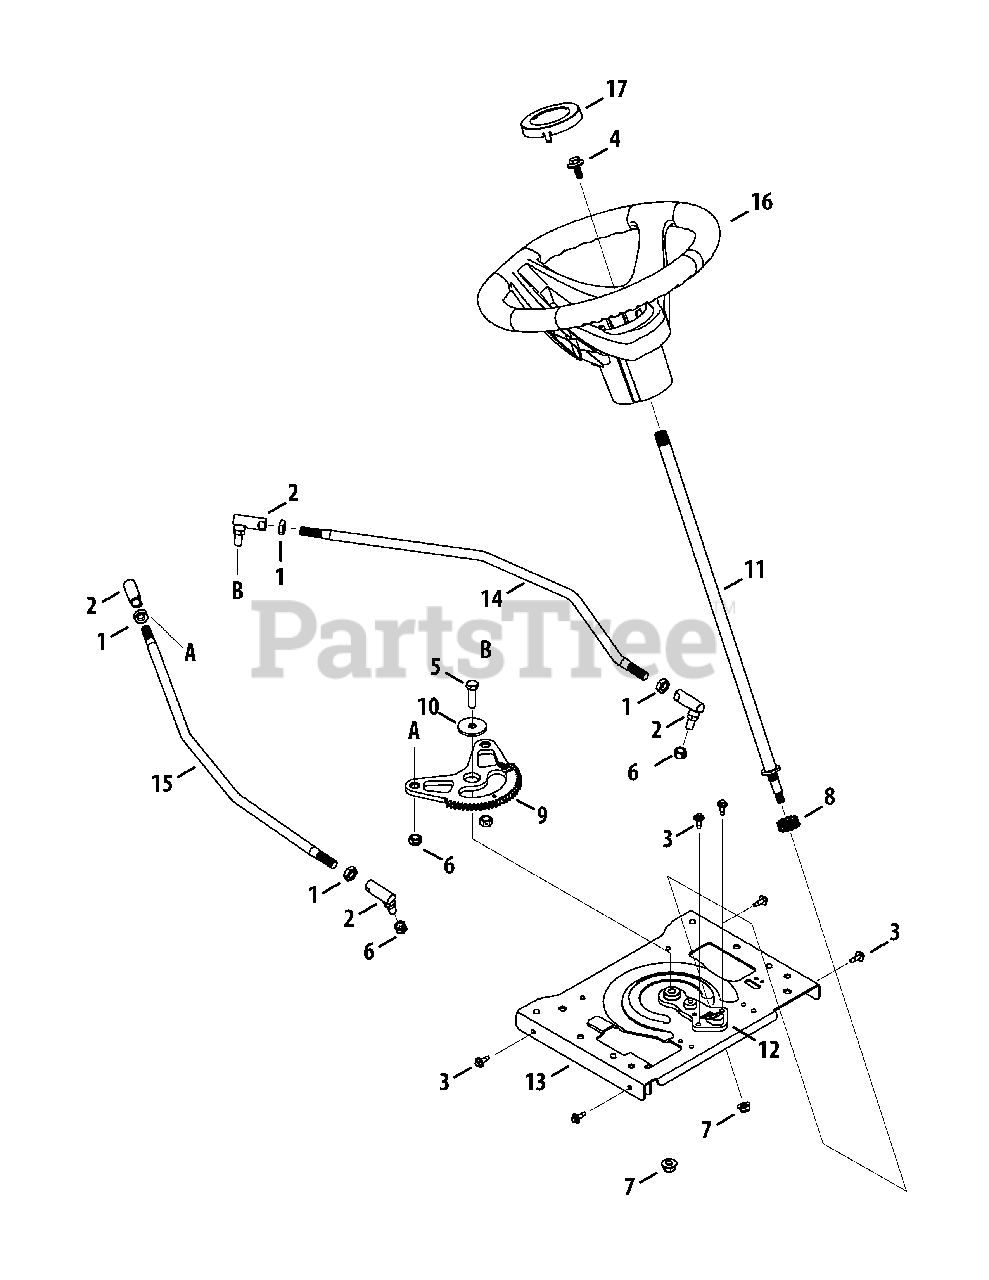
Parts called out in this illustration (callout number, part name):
1	Jam Nut, 7/16-20
2	Ball Joint, 7/16-20, Lock
3	Screw, M6-1 x .625
4	Screw, 5/16-24 x .850
5	Hex Cap Screw, 3/8-16 x 1.25
6	Nut, Hex Lock, 3/8-24, Grb
7	Nut, Flange Lock, 3/8-16, Grf, Nylon
7	Nut, Flange Lock, 5/16-18, Grf, Nylon
8	Pinion Gear, 13T
9	Steering Gear
10	Flat Washer, .390 x 2.49 x .119
11	Shaft, Steering, .625 OD x 20
12	Steering Support
14	Steering Rod, LH
15	Steering Rod, RH
16	Steering Wheel
17	Cap, Steering Wheel
